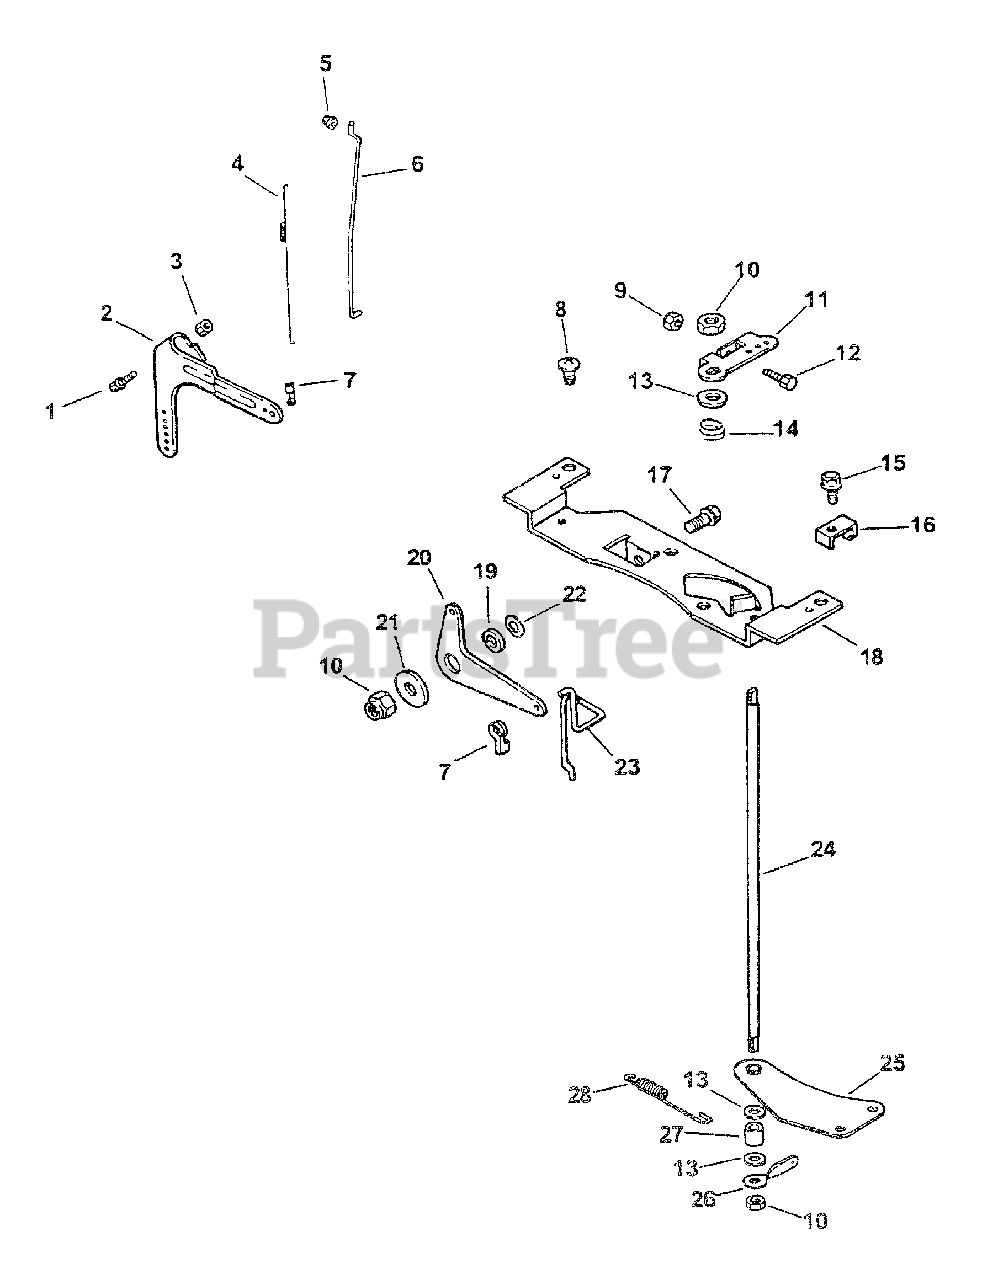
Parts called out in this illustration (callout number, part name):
1	Screw, Hex Flange
2	Lever, Governor
3	Nut, Hex Flange
4	Spring, Linkage
5	Bushing, Linkage Retaining
6	Linkage, Throttle
7	Bushing, Throttle Linkage
8	Screw, Phillips Head
10	Nut, Hex Lock
11	Lever, Throttle Control
12	Screw, Hex Cap
13	Washer, Plain 1/4"
14	Spring, Throttle Shaft
15	Screw, Hex Flange
16	Clamp, Cable
17	Screw, Hex Flange
18	Bracket, Control
20	Lever, Choke
21	Washer, Plain 1/4"
22	Washer, Spring 3/8"
23	Linkage, Choke
24	Shaft, Throttle
25	Bracket, Throttle Shaft
26	Lever, Throttle Control
28	Spring, Governor
